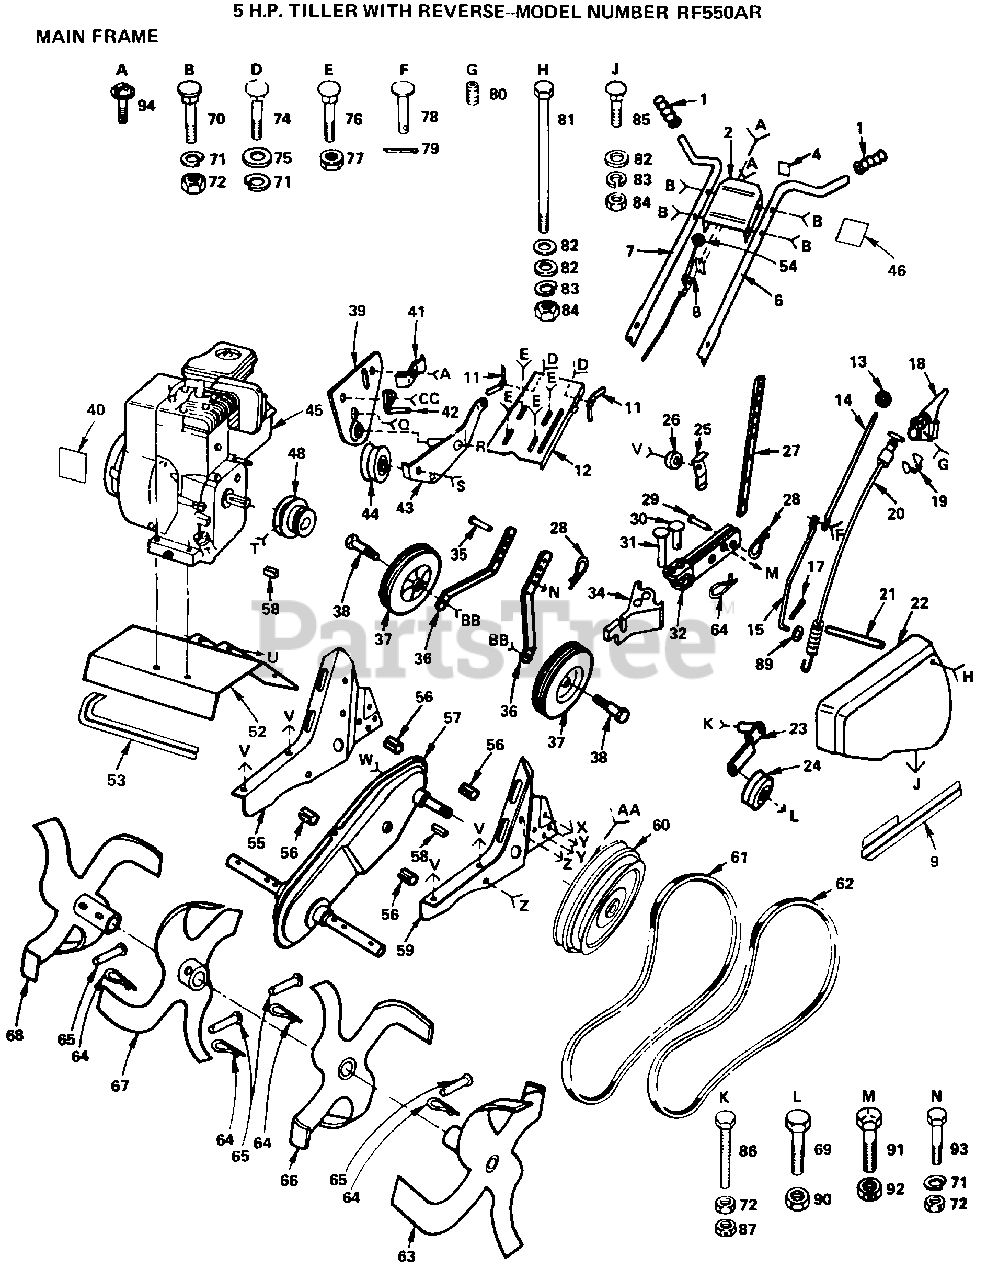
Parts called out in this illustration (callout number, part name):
2	BRACKET - HANDLE
4	DECAL - THROTTLE
8	THROTTLE CONT TI
9	DECAL - BELT GUARD
14	ROD REVERSE TI
15	REVERSE ROD TI
17	COTTER PIN
18	CONTROL LEVER TI
19	E-RING
20	CABLE CLUTCH T
21	SPLIT SPACER
25	STAKE SPRING TI
28	SPRING.RETAINER
31	RIVET
35	DRILLED RIVET RT
37	WHEEL TI
38	BOLT M
41	CONDIUT CLIP T
43	REVERSE IDLER T
44	PULLEY W/SPACER
46	DECAL - HANDLE BRACKET
48	ENGINE PULLEY TI
53	DECAL - TINE SHIELD
56	SPLIT SPACER RT
58	KEY T
63	TINE WELDMENT TI
64	RETAINER.SPRING
65	RIVET.PAN HD.1.75
68	TINE WELDMENT TI
71	LOCKWASHER
72	NUT.HEX.5/16-18
74	BOLT
75	WASHER
77	NUT
78	RIVET.RD.HD.DRILL
80	SCREW
82	WASHER
83	LOCKWASHER
85	BOLT
89	WASHER
90	NUT
92	GRIPCO NUT
